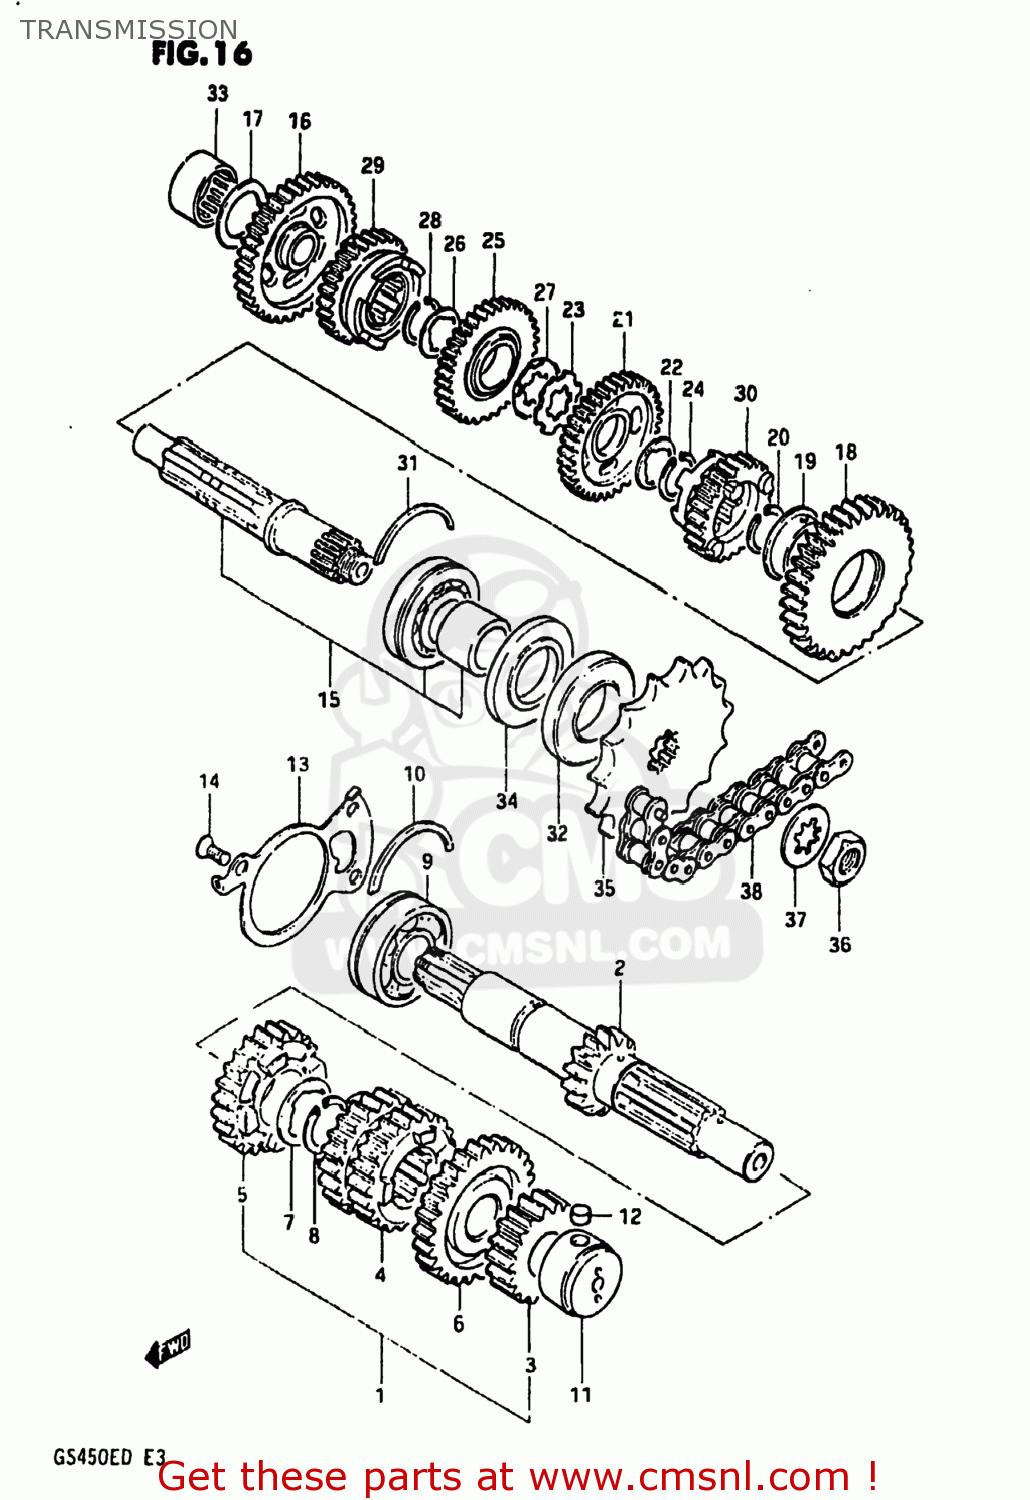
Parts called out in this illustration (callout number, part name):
1	SHAFT,COUNTER
2	SHAFT,COUNTER
3	GEAR,2ND DRIVE(NT:18)
4	GEAR,THIRD DRIVE
5	GEAR,FIFTH DRIVE
6	GEAR,SIXTH DRIVE
7	WASHER
8	CIRCLIP
9	BEARING(25X62X17)
10	C-RING
11	ROLLER BEARING (20X34X2
12	PIN
13	PLATE,COUNTERSHAFT BEARING
14	SCREW
15	SHAFT,DRIVE
16	GEAR,FIRST DRIVEN
17	WASHER
18	GEAR,SECOND DRIVEN
19	BUSHING
20	CIRCLIP
21	GEAR,THIRD DRIVEN
22	WASHER,LOCK
23	WASHER,LOCK
24	CIRCLIP
25	GEAR,FOURTH DRIVEN
26	WASHER,LOCK
27	WASHER
28	CIRCLIP
29	GEAR,5TH DRIVEN(NT:25)
30	GEAR,SIXTH DRIVEN
31	C-RING
32	SEAL,OIL(32X62X7)
33	ROLLER BEARING (20X34X1
34	SEAL,OIL(32X62X5.5)
35	SPROCKET,ENGINE(NT:16)
36	NUT
37	WASHER
38	CHAIN ASSEMBLY,DRIVE
